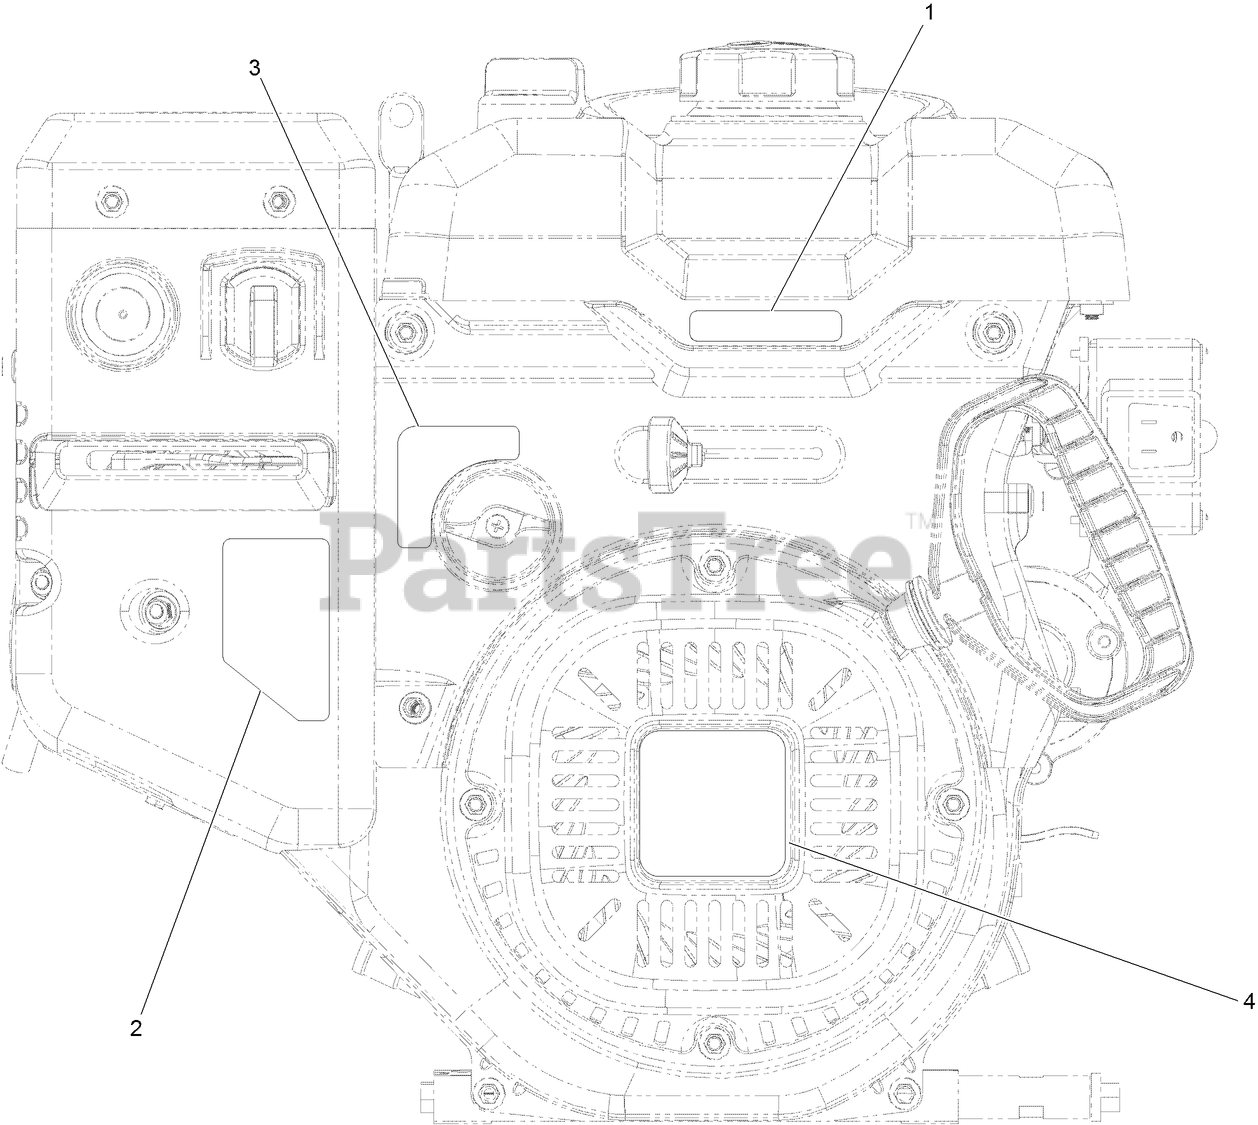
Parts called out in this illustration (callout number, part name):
1	DECAL-THROTTLE
2	DECAL-CONTROL, ENGINE
3	DECAL-VALVE, FUEL
4	DECAL-RECOIL
